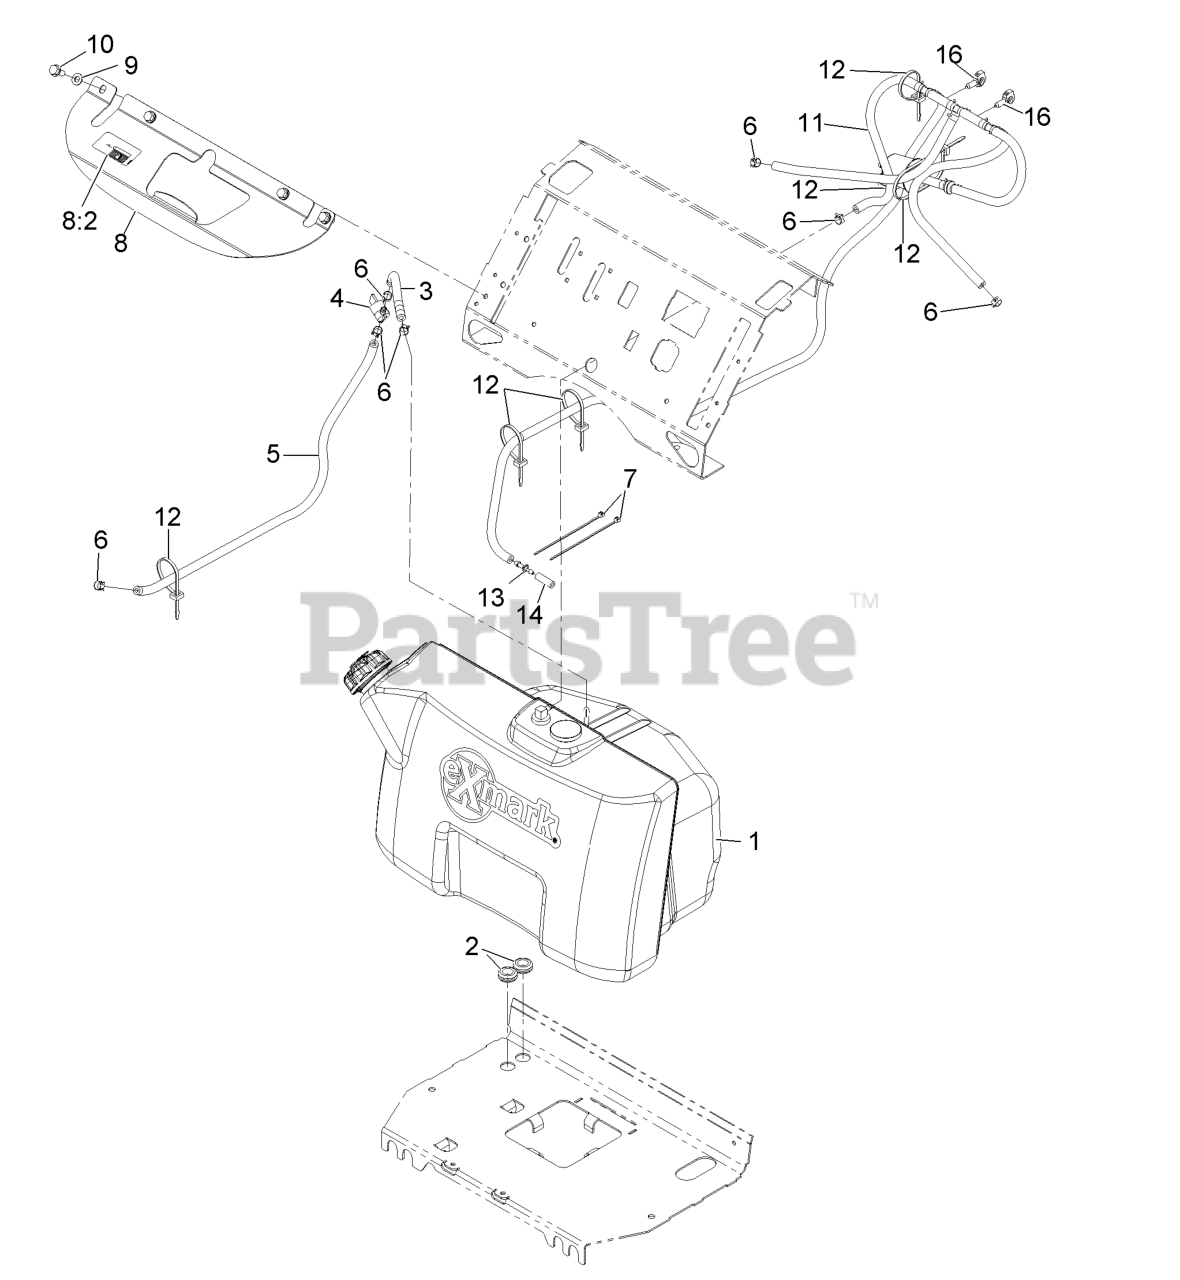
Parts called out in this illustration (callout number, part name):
2	GROMMET
3	HOSE-FUEL
4	VALVE-FUEL
5	HOSE-FUEL
6	CLAMP-HOSE
7	TIE-CABLE
8	BRACKET-TANK
8:2	DECAL-FILL, FUEL
9	WASHER-FLAT
10	SCREW-THD ROLL, HWH
11	VENT ASM
12	TIE-CABLE
13	FITTING-STRAIGHT
14	HOSE-FUEL
16	CLIP-HARNESS
